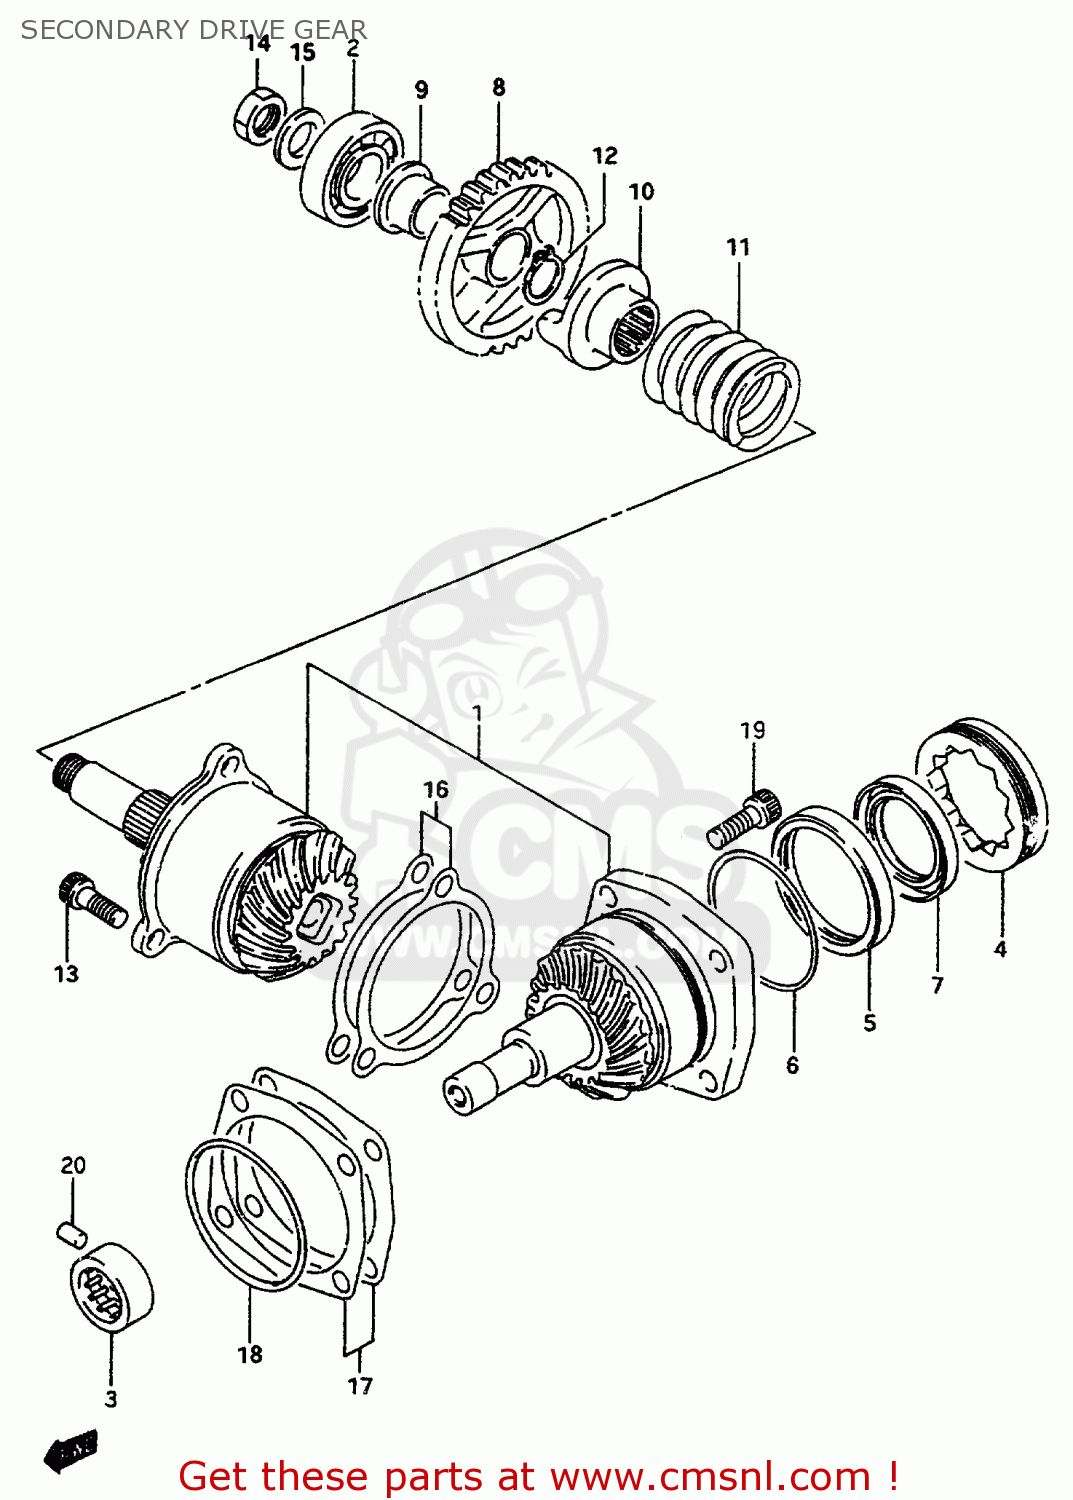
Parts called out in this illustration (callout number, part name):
1	GEAR & HOUSING SET,SECONDARY
2	BEARING(20X52X15)
3	BEARING(20X34X16)
4	STOPPER,SEC DRIVEN BEARING
5	HOUSING,OIL SEAL
6	O RING(D:1.2,ID:59.6)
7	SEAL,OIL(38X54X8.5)
8	GEAR,REDUCTION DRIVEN(NT:30)
9	BUSH,REDUCTION DRIVEN GEAR
10	DOG,OUTPUT CAM
11	SPRING
12	CIRCLIP
13	BOLT
14	NUT
15	WASHER(16X29X4)
16	SHIM SET,SEC DRIVE GEAR
17	SHIM SET,SEC DRIVEN HOUSING
18	O RING(D:2.1,ID:66.2)
19	BOLT
20	PIN
